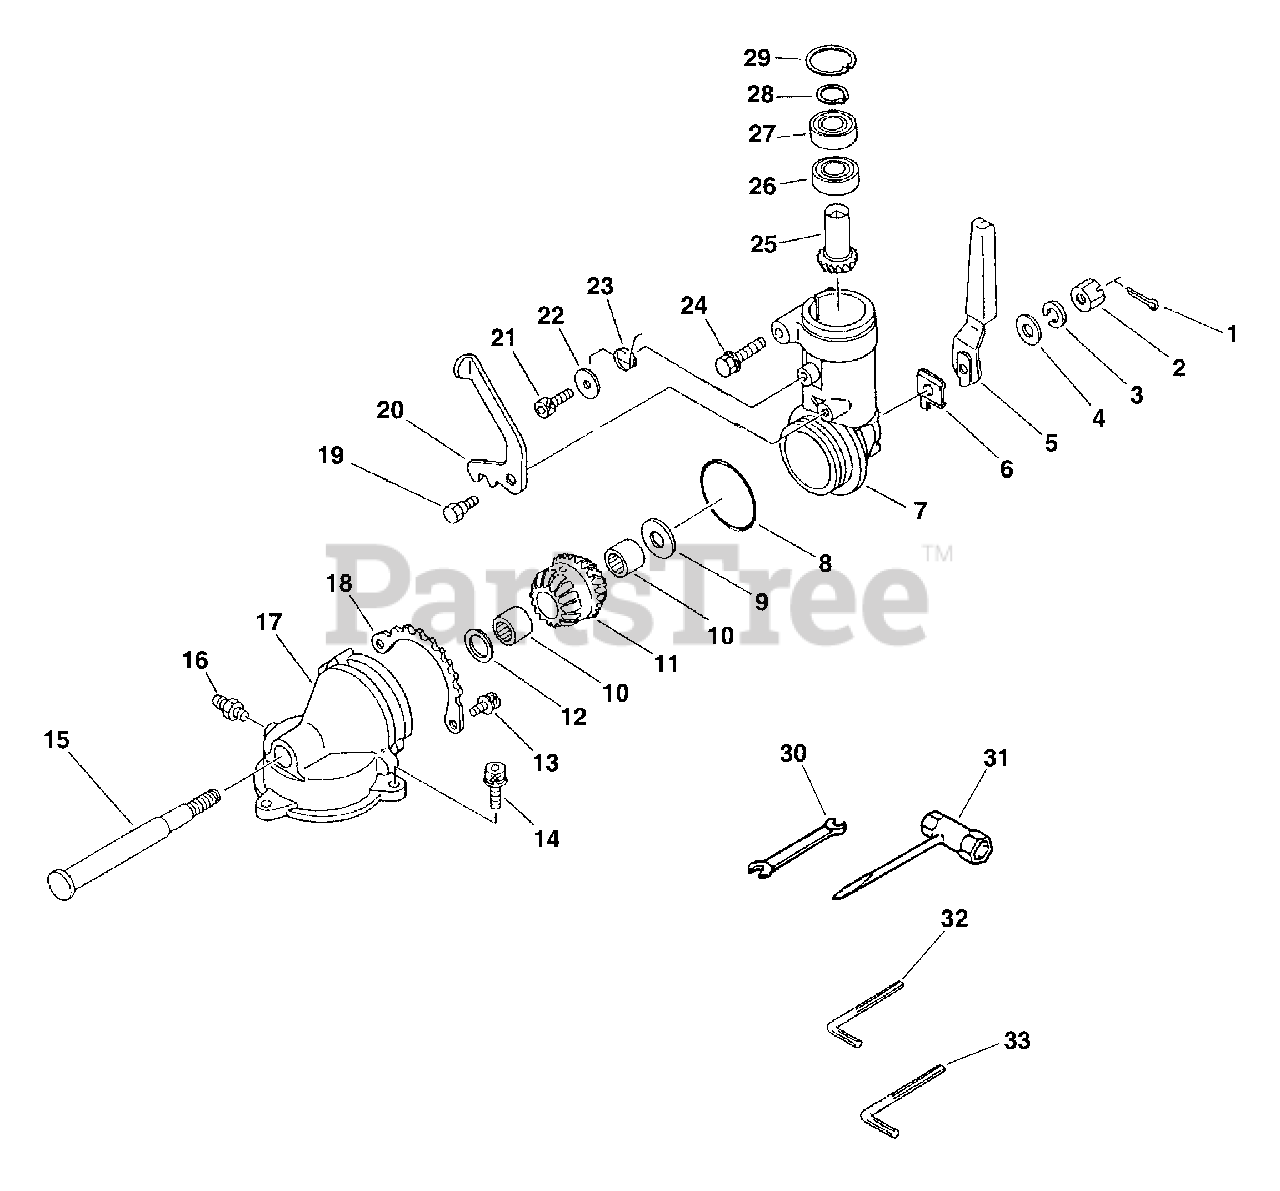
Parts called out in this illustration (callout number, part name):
1	PIN, SPLIT - 1.6X16
2	NUT - 6 -- SLOTTED
3	LOCKWASHER - 6
4	WASHER, THRUST
5	PIECE, LEVER
6	PLATE, ANGLE
7	CASE, GEAR
8	O-RING - 32
10	BEARING, NEEDLE - 8
11	GEAR - BEVEL
12	WASHER
13	SCREW - 4X10
14	SCREW - 5X18
15	GEAR - SHAFT
16	FITTING, GREASE
17	LID, GEAR CASE
18	RESETTER, LATCH
19	BOLT - 5
20	PAWL
21	SCREW - 5X14
22	WASHER - 5
24	BOLT - 5X35
25	GEAR - DRIVE
26	BEARING, BALL - 6900
27	BEARING, BALL - 6900Z
28	RING, RETAINING - 10
29	RING, RETAINING - 22
30	SPANNER - 8X10mm
31	T-WRENCH - 17X19mm
32	HEX KEY - 3mm
33	HEX KEY - 4mm
